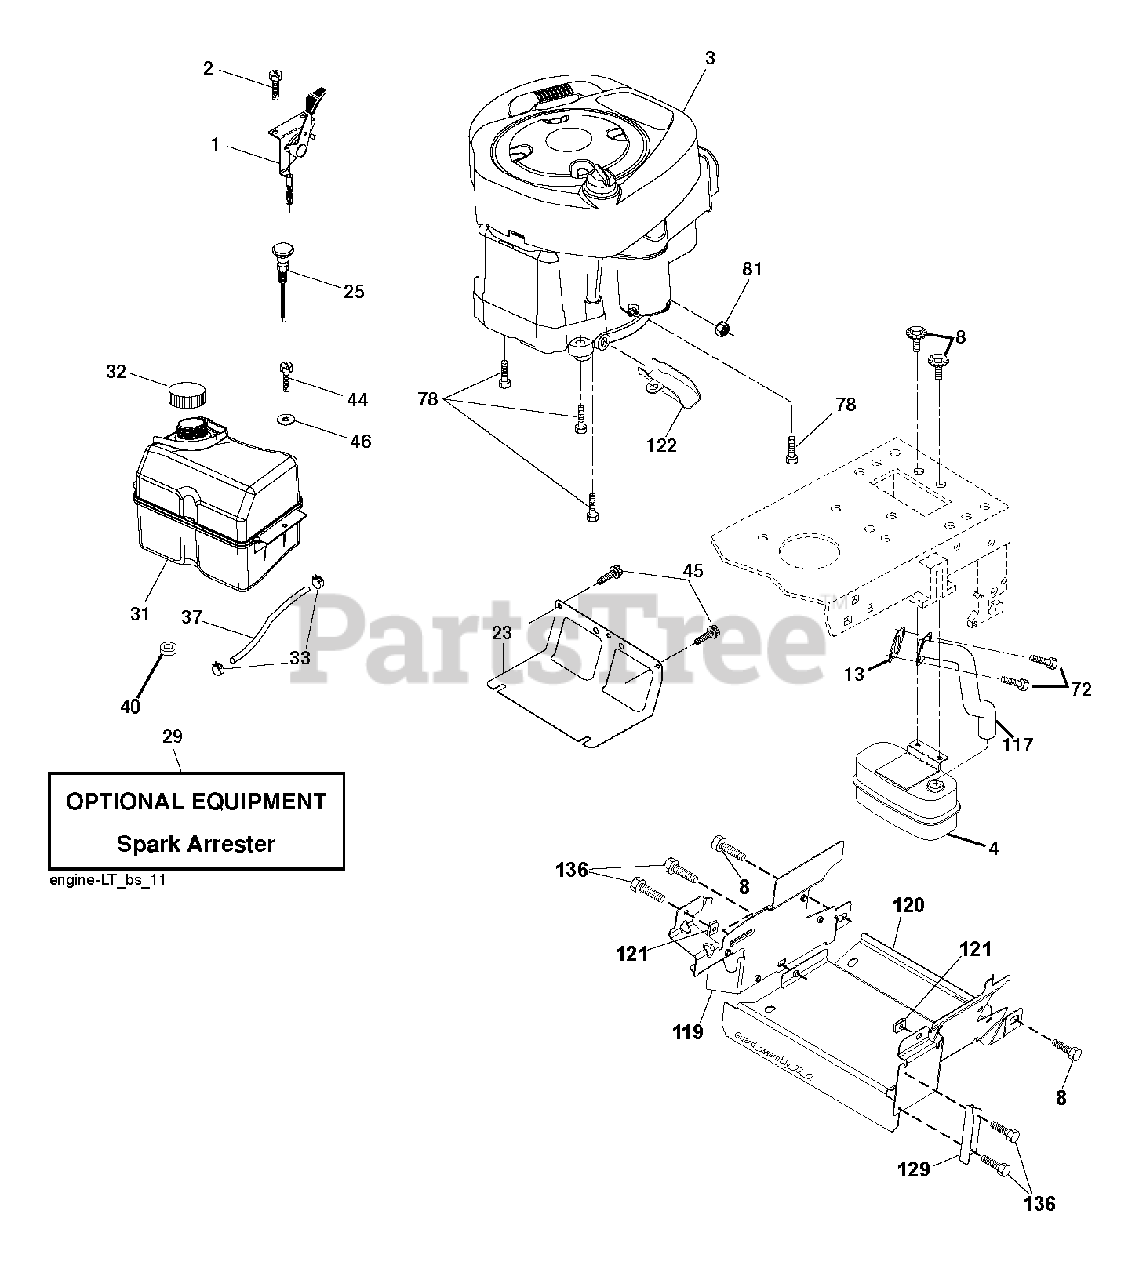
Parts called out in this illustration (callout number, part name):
1	CONTROL TH/CH FLAG
2	SCREW
4	MUFFLER.SINGLE.CYL.KOHL/B&S
8	BOLT, 5/16-18 X 1 3/4
13	REPL BY 532 27 22-93
23	SHEILD.BROWNING.DBR.GUARD
29	ARRESTER SPARK (OPTIONAL)
32	CAP ASM.FUEL.2.25"FR.
33	HOSE CLAMP
37	LINE.FUEL.20
40	GROMMET T
44	SCREW HEXWSHR 1/4-20X3/4
45	SCREW, 3/8-16X3/4
72	SCREW.SOCKET HD.5/16-1
78	SCREW.3/8-16
81	NUT
117	EXHAUST.TUBE.B&S.
122	EXTENSION DRAIN OIL
136	SCREW.1/4-20X5/8
